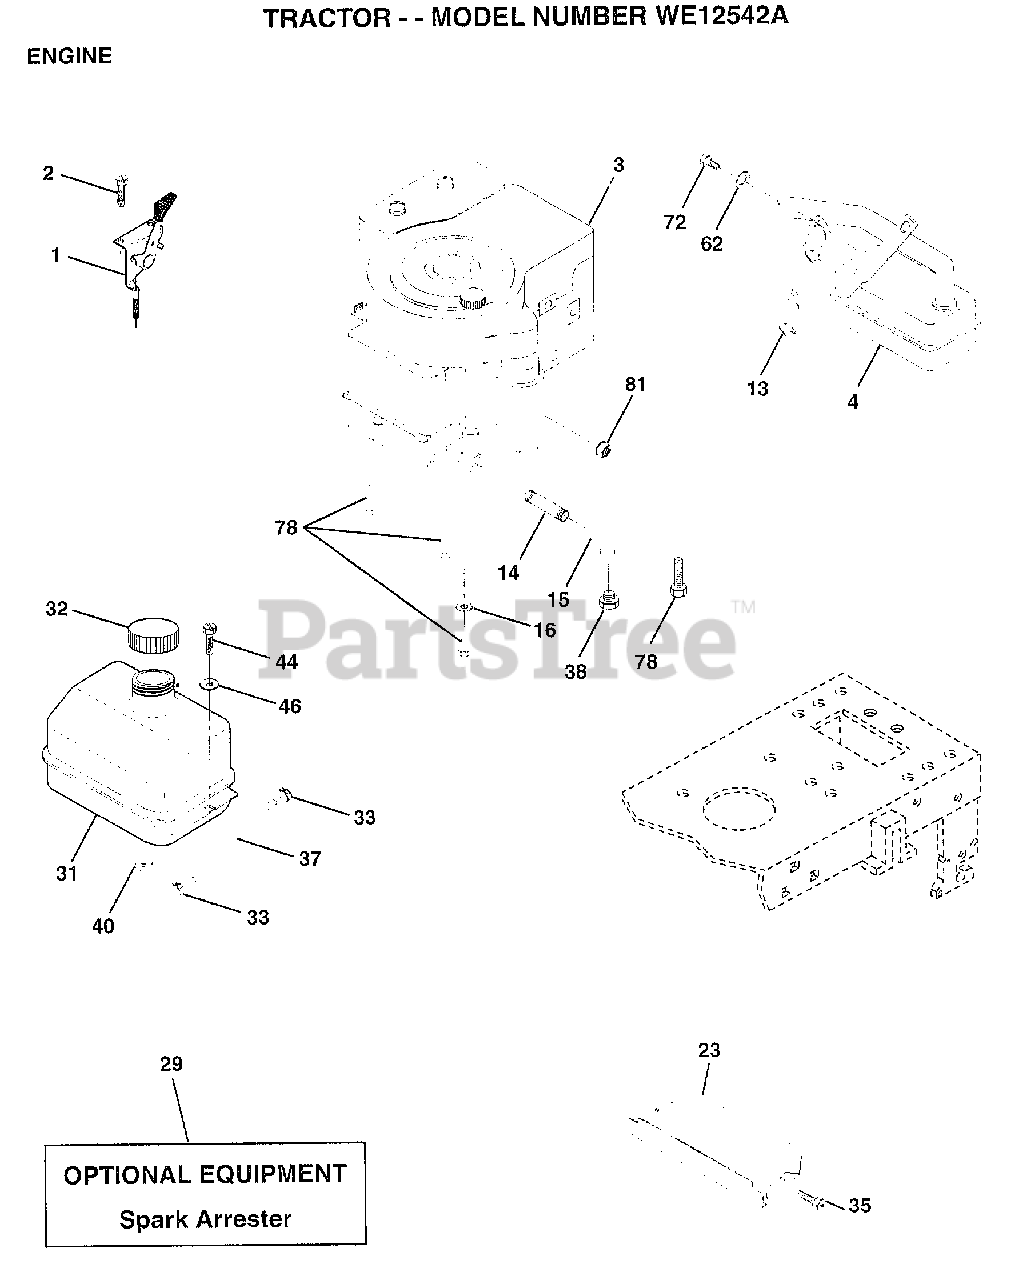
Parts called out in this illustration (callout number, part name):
1	CONTROL THROTTLE
2	SCREW LT
4	MUFFLER
13	GASKET ENG 1 313 LD TIN PLATED
14	PIPE NIPPLE
15	ELBOW
16	LOCKWASHER
23	SHIELD.BRN/DBR.GD
31	TANK.FUEL.LT.
32	CAP ASM FUEL
33	HOSE CLAMP
35	SCREW
37	LINE FUEL
44	SCREW HEX CRT
46	WASHER
62	LOCKWASHER
72	SCREW
78	SCREW
81	NUT
